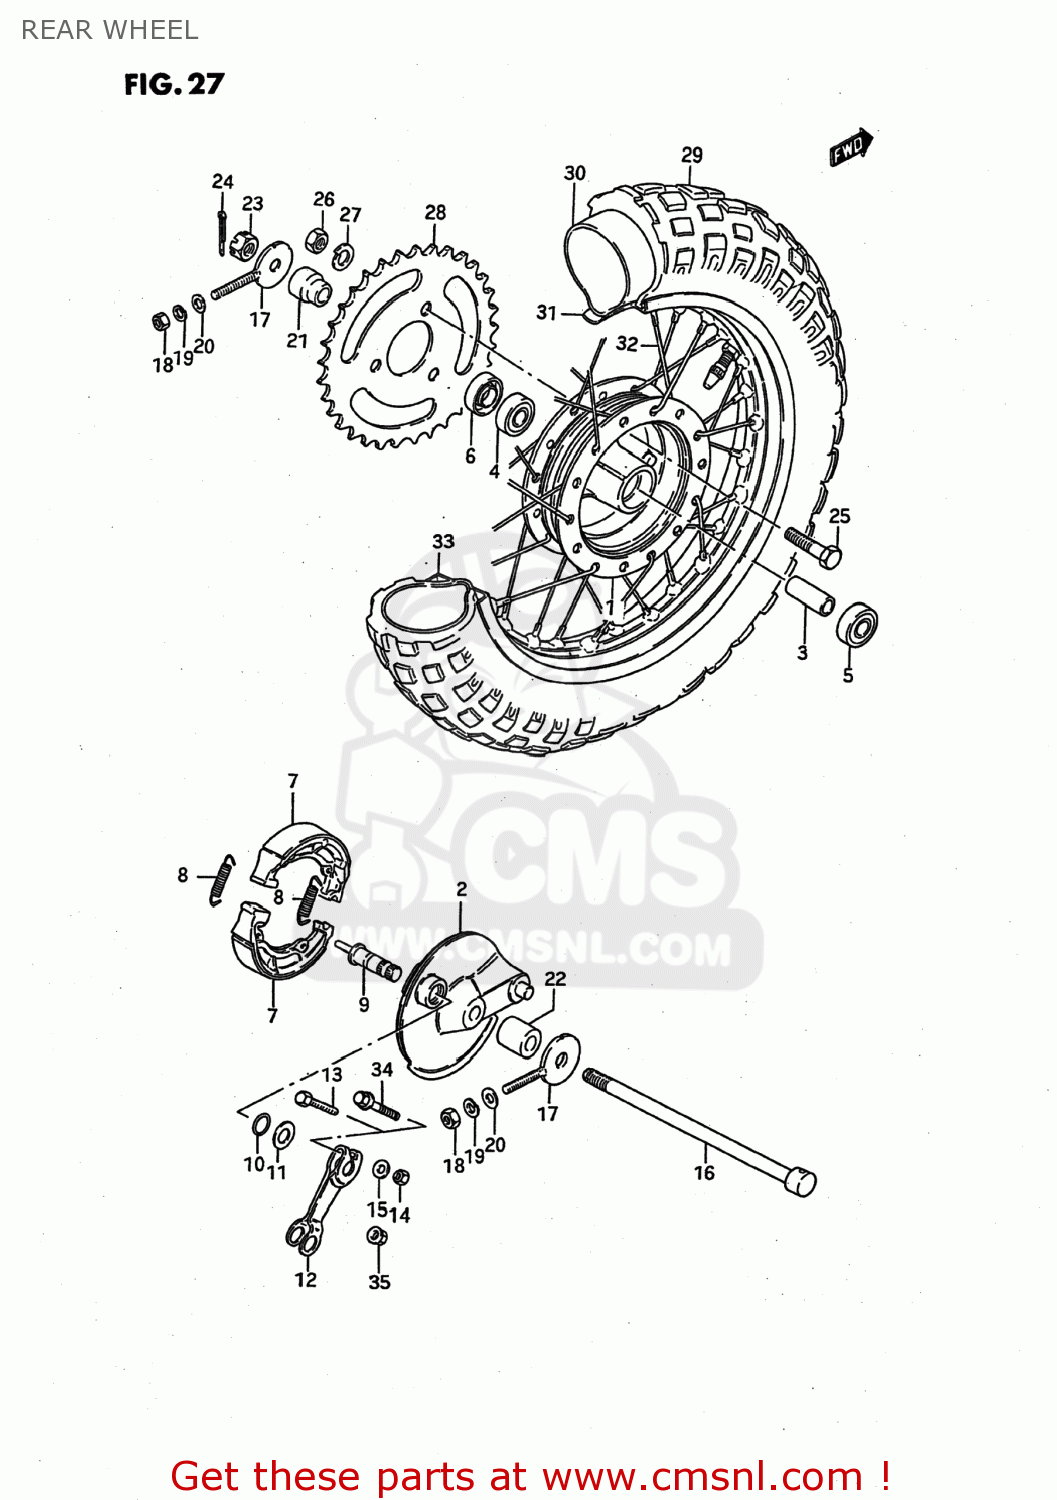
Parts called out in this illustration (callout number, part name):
1	HUB,RR WHEEL
2	PANEL,RR BRAKE ANCHOR
3	SPACER (10.2X16X55)
4	BALL BEARING K
5	BEARING
6	SEAL,OIL(15X27X6)
7	SHOE,BRAKE
8	SPRING(L:35.8)
9	CAM,BRAKE
10	O RING(D:2.4,ID:9.8)
11	WASHER (10.5X18X1)
12	LEVER,RR BRAKE CAM
13	BOLT
14	NUT 5MM
15	WASHER
16	AXLE,RR
17	ADJUSTER,CHAIN
18	NUT 6MM
19	WASHER,LOCK
20	WASHER
21	SPACER,RR AXLE,L
22	SPACER,RR AXLE,R
23	NUT
24	PIN 20X20
25	BOLT(8X36)
26	NUT
27	LOCK WASHER
28	SPROCKET,RR
29	TIRE
30	TUBE,INNER
31	PROTECTOR,INNER TUBE
32	SPOKE SET,RR
33	RIM,WHEEL
34	BOLT
35	NUT
